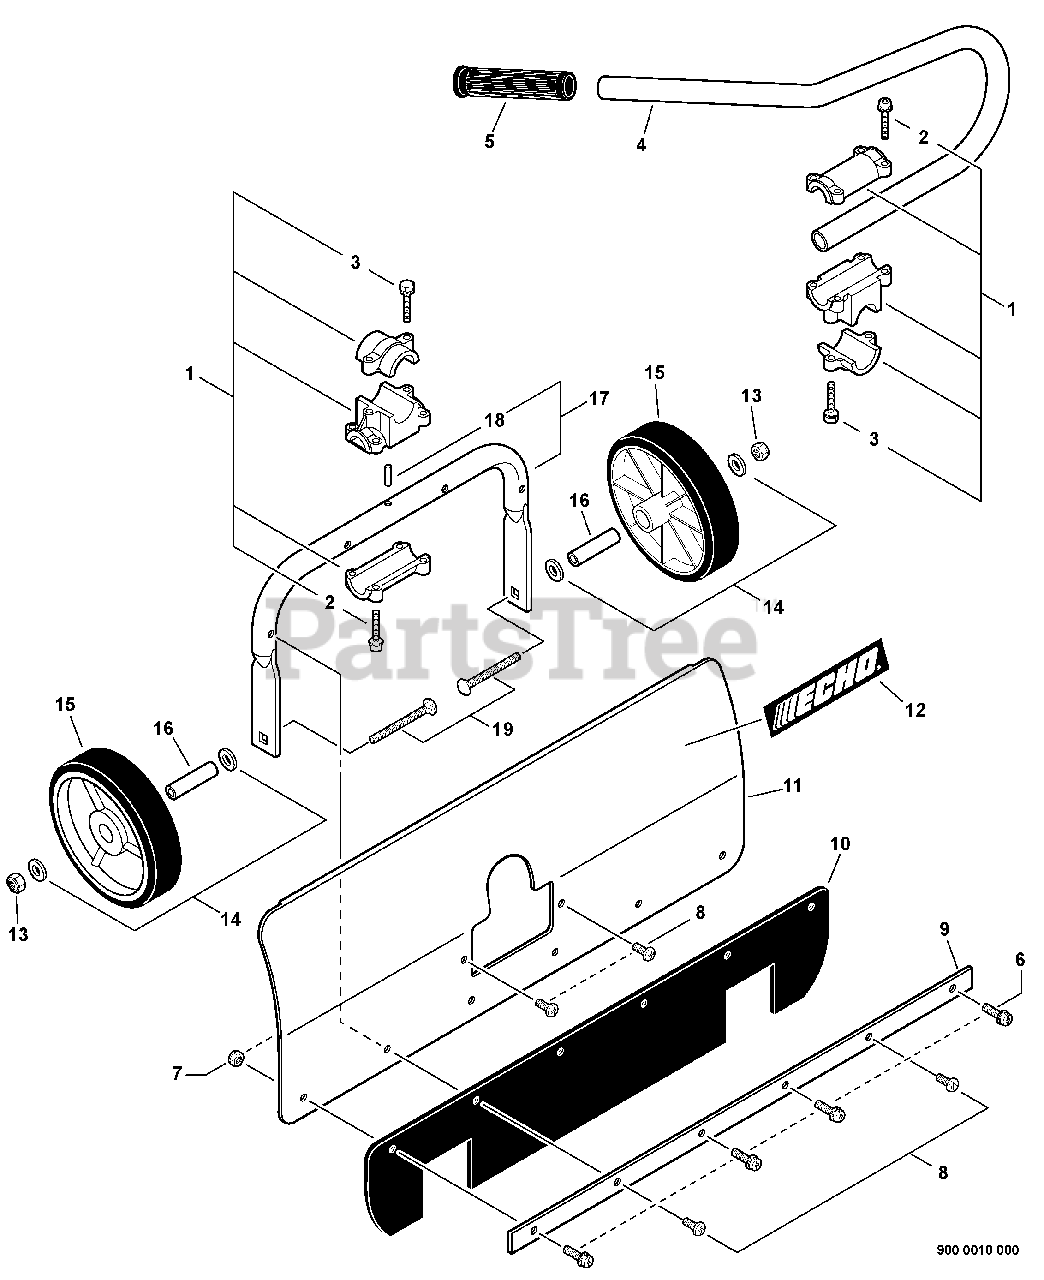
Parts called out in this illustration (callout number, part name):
1	BRACKET KIT, HANDLE
2	BOLT 5×25
3	BOLT - 6×30
4	HANDLE, FRONT
5	GRIP, HANDLE
6	SCREW 5×16
7	NUT, LOCK M5
8	SCREW, TAPPING
9	RETAINER, FLAP
10	SHIELD, DEBRIS
12	LABEL, ECHO BLOWER TUBE
14	WASHER 8.5×16×1.2
15	WHEEL
16	COLLAR 12
17	BRACKET, FRONT AXLE
18	PIN, LOCATING 0.17 OD×0.75 L
19	BOLT 5/16"-18×2-1/2"
